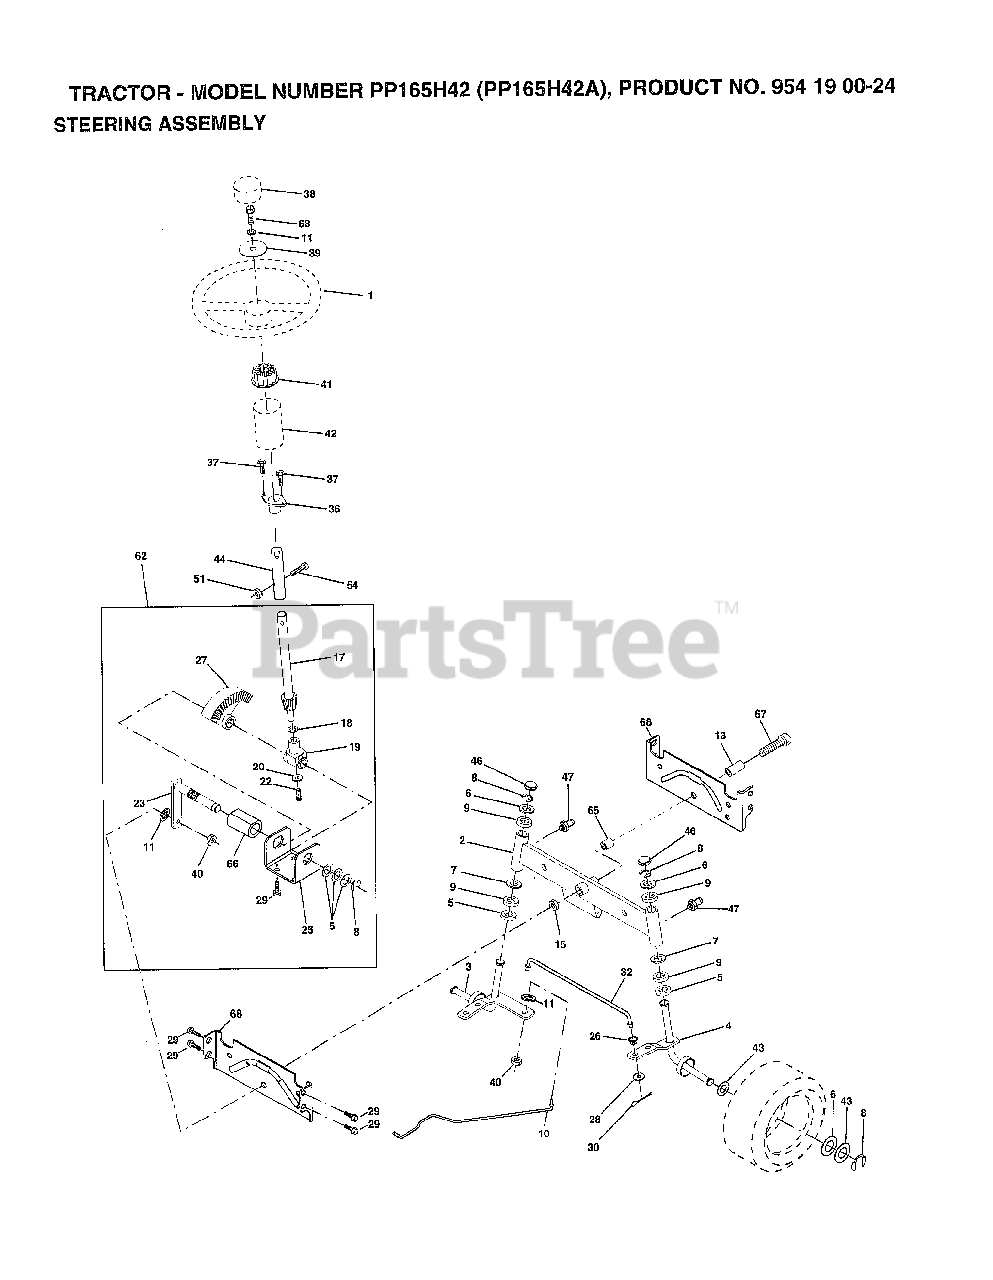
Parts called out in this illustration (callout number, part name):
2	AXLE ASM
3	SPINDLE.ASM.LH
4	"SPINDLE ASM,RH"
5	WASHER .T
6	WASHER
7	WASHER
8	RING
9	COL. SRTG. BEAR.
10	DRAGLINK-STAMPED
11	LOCKWASHER
13	BEARING AXLE
15	"NUT-LOC,FLANGE LT"
17	SHAFT ASM STEERIN
18	THRUST WASHER
19	SUPPORT.SHAFT
22	SCREW HEX SOC1/4-
25	BRKT-STEERING
26	BUSHING.DRAGLINK
27	GEAR SECTOR
28	WASHER
29	SCREW
30	COTTER PIN
32	TIE ROD
36	BUSHING.STEERING
37	"SCREW-TT,10-32 FL"
38	"INSERT,STR WHEEL"
39	WASHER T
40	GRIPCO NUT
41	ADAPTER LT
42	BOOT.STEER.PL
44	EXT SHAFT STEERIN
46	CAP
47	ZERK M
51	NUT
54	BOLT
62	KIT STEERING ASM
63	BOLT
65	SPACER AXLE
66	"BEARING-ARM,PITMA"
67	BOLT
68	BRACE AXLE
